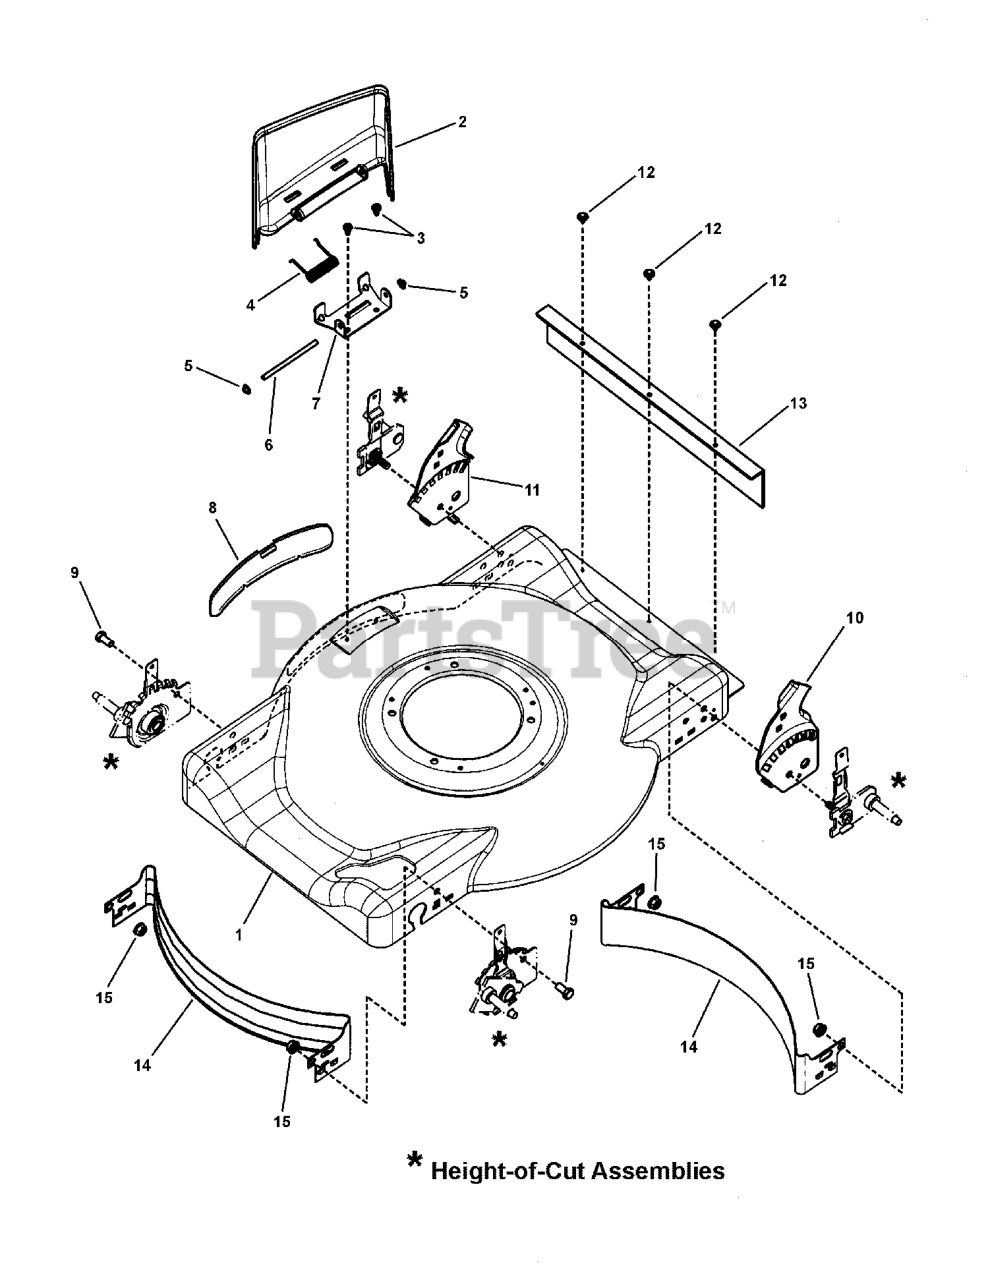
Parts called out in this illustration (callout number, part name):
1	DECK, 22" WBM, Side Discharge
2	CHUTE, Plastic Side Discharge
3	SCREW, 1/4-20 x .550 Pan Head Torx (T-30)
4	SPRING, Torsion, Chute
5	PUSHNUT, 1/4"
6	ROD, Pivot, Mulch Cover
7	BRACKET, Chute Low Cost
8	MULCH PLATE
9	BOLT, 3/8-16 x 3/4" Hex Head, GR 5
10	BRACKET, Handle, LH Low Cost
11	BRACKET, Handle, RH Low Cost
12	SCREW, #10-24 x 1/2" Hex Washer Self-Tap - Sems
13	REAR GUARD
14	BAFFLE, 22" Side Discharge
15	NUT, 3/8-16, Hex Flange Lock GR 5
